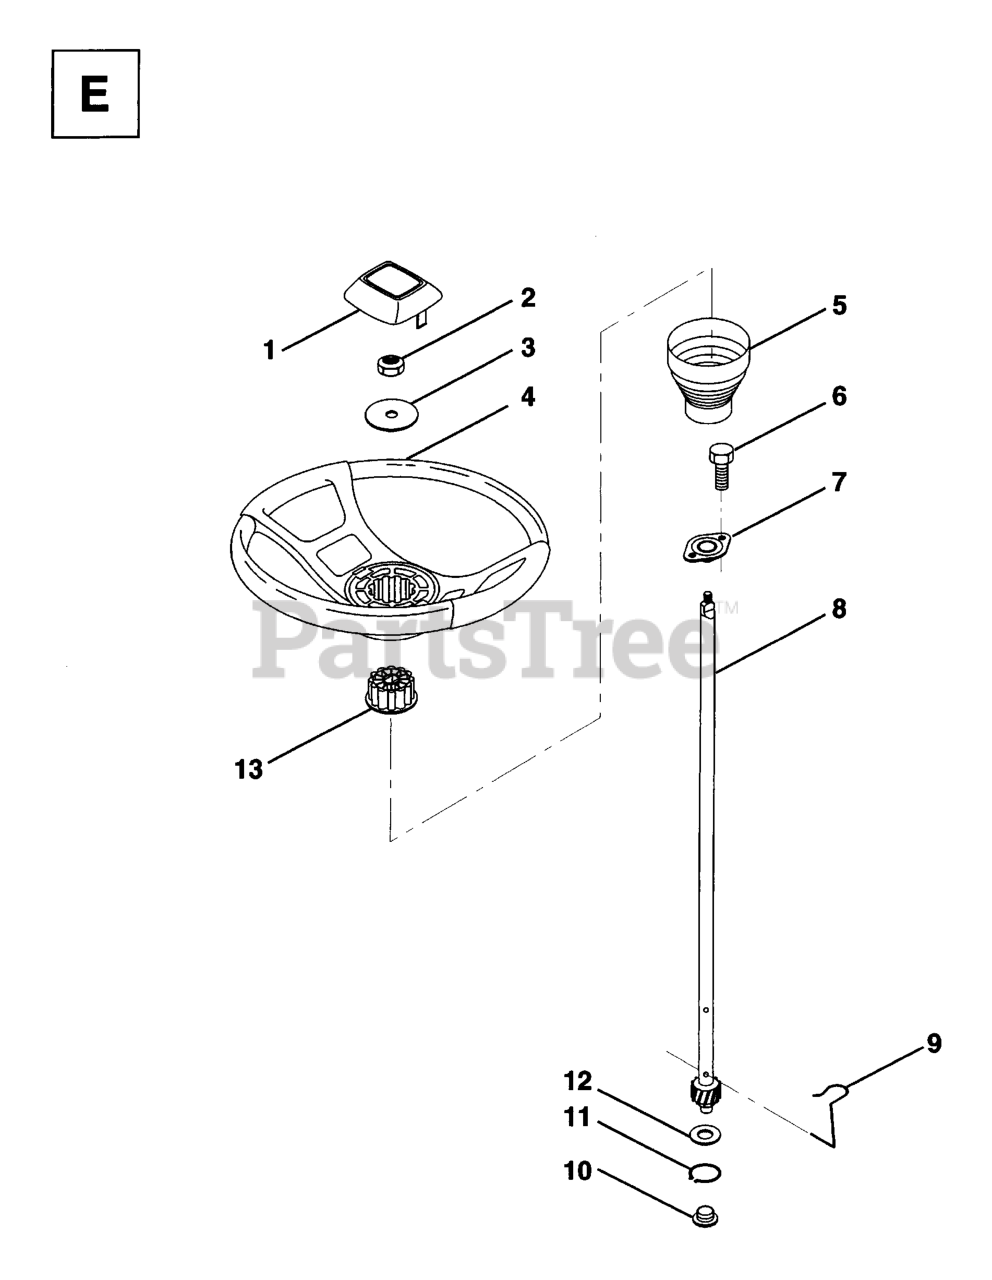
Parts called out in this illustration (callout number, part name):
1	INSERT,STR WHEEL
2	GRIPCO NUT
3	WASHER T
4	STEERING WHEEL
5	STEERING SLEEVE
6	SCREW LT
7	BUSHING-STRG LT
8	SHAFT STEERING
9	STEERING CLIP
10	BUSHING STEER LWR
13	ADAPTER-WHEEL LT
